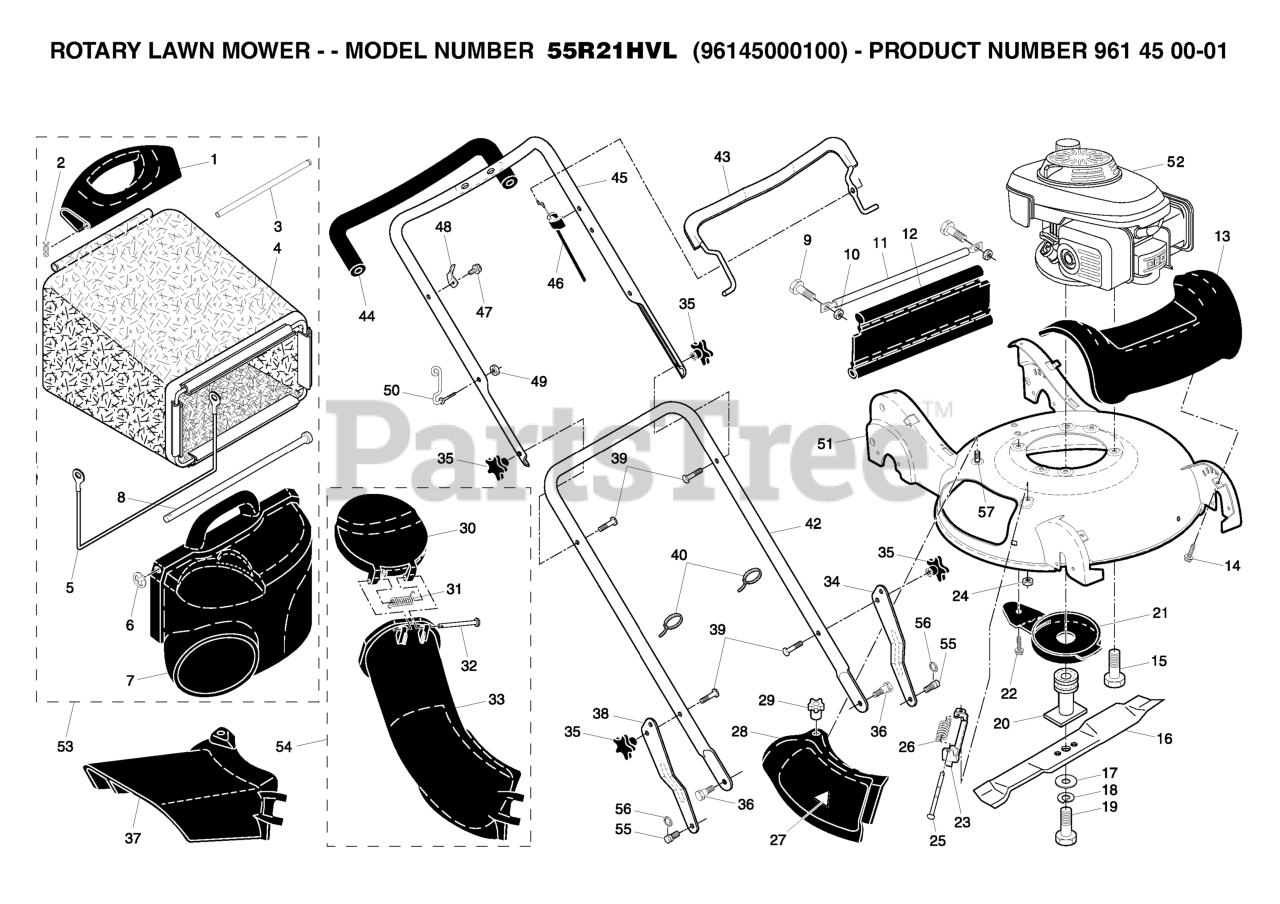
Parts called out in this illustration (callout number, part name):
1	HANDLE.GRASSBAG.REAR.H-GRAY
2	COTTER PIN (3 2)(2 2MC)
3	ROD.REAR.HANDLE.YELLOW
4	GBAG.5211247.SILVER
5	FRAME, GRASSBAG
7	DOOR, GRASSBAG
8	ROD, PIVOT
10	LOCKNUT.NYLOC.1/4-20
11	TUBE, REAR SKIRT
12	SKIRT, REAR
13	COVER, FRONT
14	SCREW
15	BOLT 3/8-16X1-1/8
16	BLADE.21.PUSH/RWGD/FWG
17	WASHER,HARDEN
18	LOCKWASHER
19	BOLT.HD.HEAD.3/8-24X2.50 (2 2)
20	ADAPTER.BLADE
21	DEBRIS SHEILD
22	SCREW 1/4X20
23	BRACKET.ASM.HINGE
24	LOCK NUT
25	ROD.HINGE.1/4"3.82"
26	SPRING.MULCH.DOOR
27	DECAL HYT
28	MULCHER DOOR
29	KNOB.MULCH.DOOR
30	CHUTE.DOOR.21.HV.H-GRAY
32	ROD.HINGE.1/4"3.82"
33	DISCHARGE CHUTE PLASTIC
34	BRACKET
35	KNOB.HANDLE.STAR.HUSQ.GRAY
36	SHOULDER BOLT
37	GUARD.CLIP.ON.21.HV.GRAY
38	BRACKET ADJ LOWER HNDLE RH
39	BOLT, HANDLE 5/16-18X1.75
40	TIE GUIDE
42	HANDLE.LOWER.GREY
43	BAIL CONTROL
44	GRIP.HANDLE.FOAM.WIDE.(1 SIDE)
45	HANDLE.ASM.UPPER.W/GRIP
46	RB ENGINE ZONE CONTROL CABLE
48	BRACKET
49	NUT
50	GUIDE.ROPE.WALK.MOWER
51	KIT.HSG.ASM.21".HV.ORNG
53	GBAG.ASM.HV'CROWN BLUE
54	CHUTE.LOWER.ASM.WALK.MOWER
55	STUD, SHOULDER
56	E-RING 7/16 RE
57	STUD.INSERT
